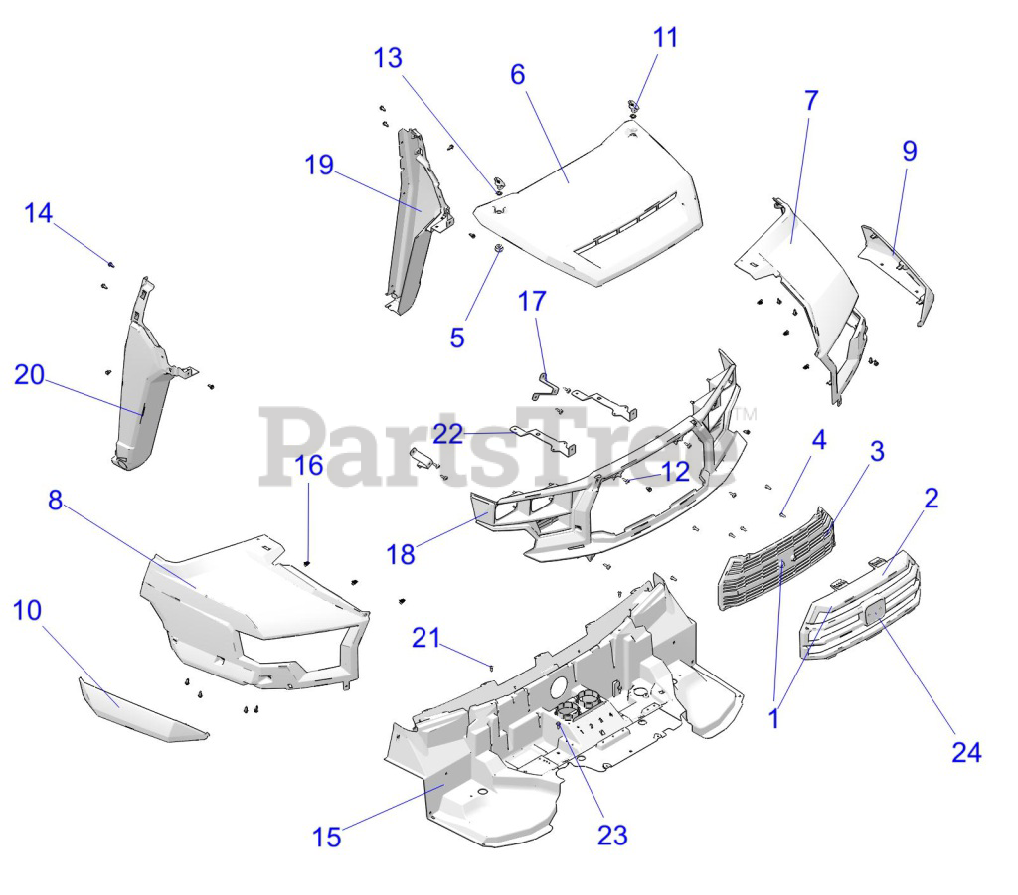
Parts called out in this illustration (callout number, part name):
1	ASM.- GRILL- GRAVELY
2	GRILL, FRONT, UPPER, BLACK
3	GRILL, UPPER, TRIM
4	SCR-TXPH-#14 X .75 HI-LO RIE
5	GROMMET-LATCH
6	HOOD-ARNS-I.RED
7	FENDER-FRONT-ARNS-LH-I.RED
8	FENDER-FRONT-ARNS-RH-I.RED
9	FLARE-FENDER-ARNS-LH-BLK
10	FLARE-FENDER-ARNS-RH-BLK
11	LATCH- 1/4 TURN
12	SCR-TXTH-M6X1.0X25 RIE
14	RIVET-TUFLOK-.315-.325X.787 (5
15	LINER-HOOD-BLK
16	CLIP- DASH TRIM METAL
18	BRKT-FASCIA MOUNT
19	BEZEL-HEADLIGHT
20	COVER-FRONT-LH-BLK
21	COVER-FRONT-RH-BLK
22	SCR-TX TRUSS-#14X3/4-HI/LO ZBK
23	BRKT-MOUNT-RADIATOR-ARNS-BLK
24	SCR-M6X1.0X20-HXHD-FLG-TDFM-BL
